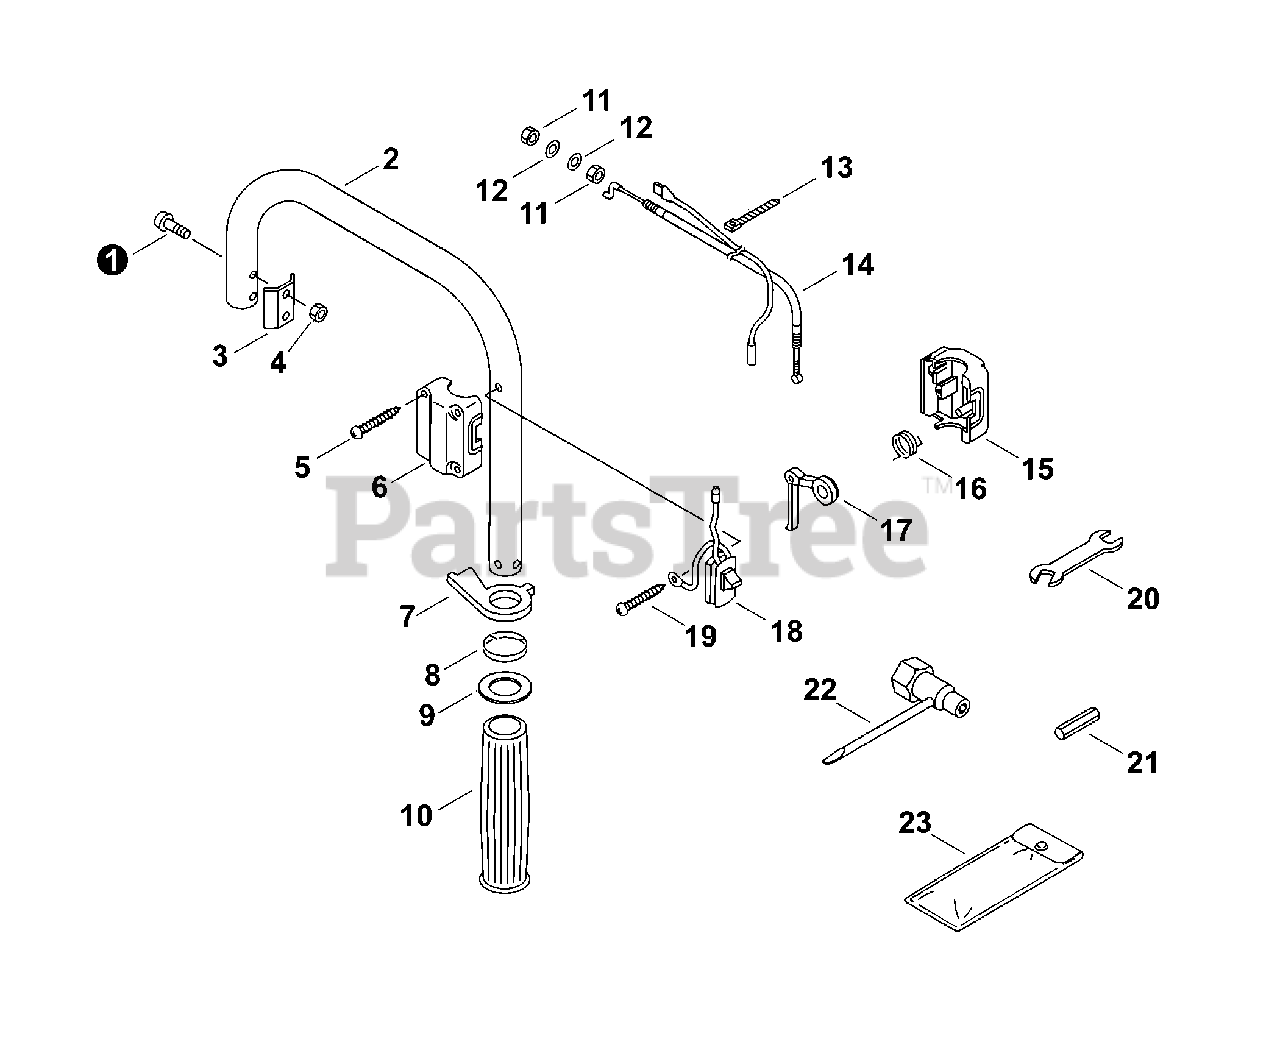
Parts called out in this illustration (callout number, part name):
1	SCREW - 5×35
2	HANDLE - REAR
3	PLATE, HANDLE
4	LOCKNUT - 5
5	SCREW - 4×25
6	BRACKET, THROTTLE CONTROL - LEFT
7	LOCKOUT, TRIGGER
8	SPRING, THROTTLE LOCK
10	GRIP, HANDLE - RIGHT
12	WASHER - 6
13	TIE, CABLE
14	CONTROL CABLE ASY
15	BRACKET, THROTTLE CONTROL - RIGHT
16	SPRING, TRIGGER
17	TRIGGER, THROTTLE
18	IGNITION SWITCH ASY
19	SCREW 4×30
20	OPEN END WRENCH
22	WRENCH 10×19
23	BAG, TOOL
